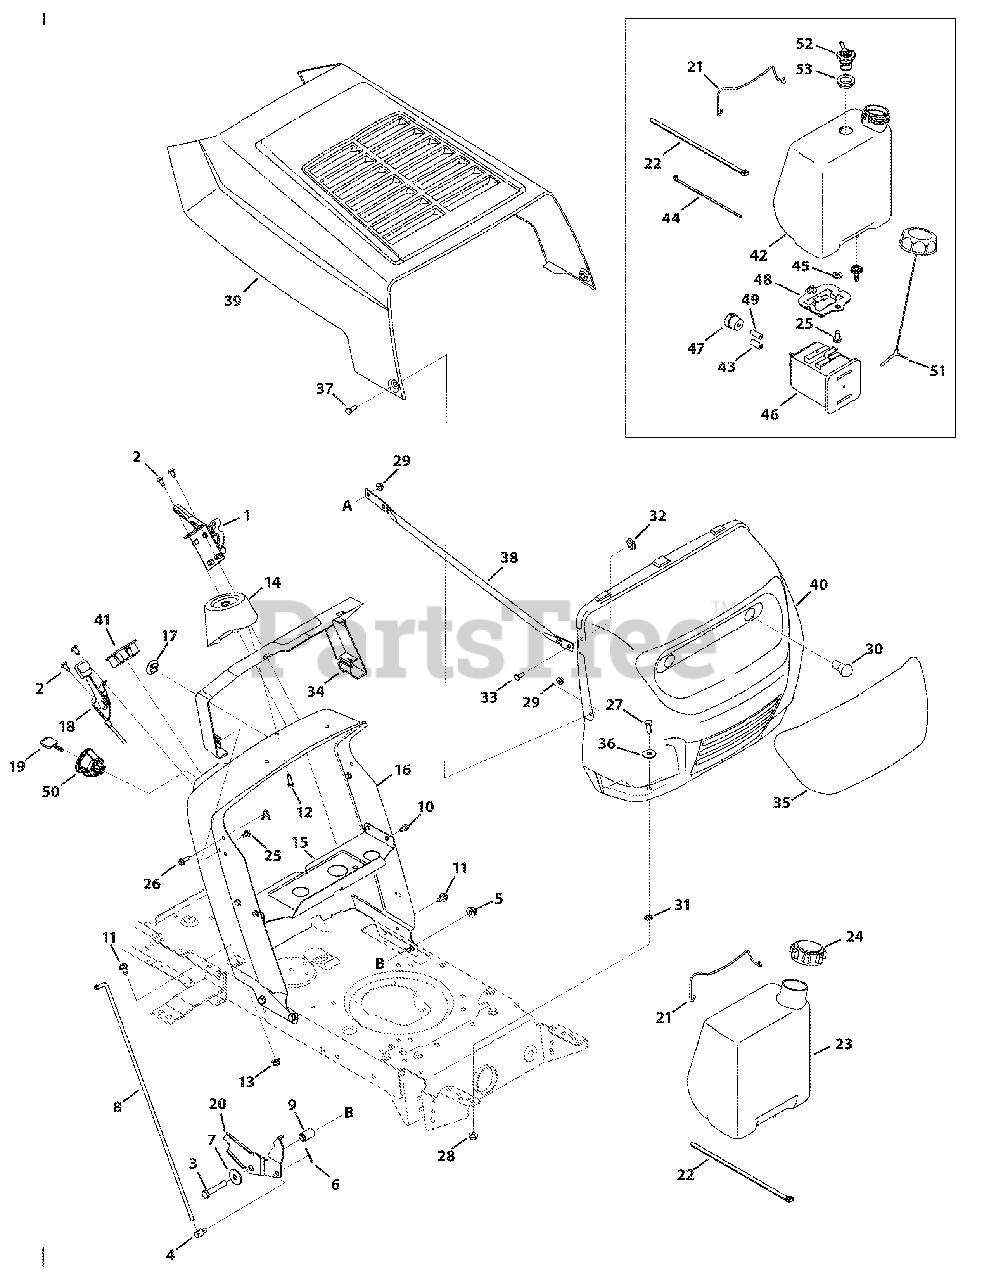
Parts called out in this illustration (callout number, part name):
1	7-Speed Control Assembly
1	6-Speed Control Assembly
2	Screw, 1/4-20 x .500
3	Hex Screw, 3/8-16 x 2.0
4	Ferrule, 1/4-20 x 1.00
5	Flangelock Nut, 3/8-16
6	Cotter Pin, 3/32 x 1.0
7	Flat Washer, .411 x 1.25 x .100
8	Speed Selector
9	Flange Spacer, .390 x .671 x 1.095
10	Hex Washer Screw, 1/4-20 x .500
11	Screw, 5/16-18 x .625
12	Screw, 1/4-15 x .750
13	Flangelock Nut, 5/16-18
14	Steering Support
15	Gas Tank Support Bracket
16	Dash, RMC
16	Dash, No RMC - Powder Black
16	Dash, No RMC - Green
17	Choke Plug
18	Throttle/Choke Cable
20	Speed Latch. RMC
21	Battery Assembly Rod
22	Cable Tie
23	1.5 Gallon Fuel Tank
24	Fuel Cap
25	Screw, 5/16-18 x .750
26	Screw, 1/4-20 x .750
27	Hex Screw, 5/16-18 x .75
28	Flangelock Nut, 5/16-18
29	Flangelock Nut, 1/4-20
30	Miniature Lamp 12V Socket
31	Speed Nut, .3125
32	Push-On Nut, .25
33	Flat Head Rivet, 1/4"
36	Flat Washer, .344 x 1.0 x .063
37	Shoulder Bolt, 1/4-20 x .375 x .125
38	Grill Support Rod
39	Hood - Red
39	Hood - Yellow
40	Grill - Red
40	Grill - Yellow
41	Ammeter
42	Fuel Tank, 1.36 Gallons
43	Fuel Hose, Yellow
44	Cable Tie
45	Flat Washer, .344 x .750 x .120
46	5 Gallon Carbon Canister
47	Vent Filter Canister
48	Canister Adaptor Bracket
49	Fuel Hose, White
50	Key Switch
51	Fuel Cap, 2.25"
52	Rollover Valve
53	Rubber Grommet, 23 x 3.55
